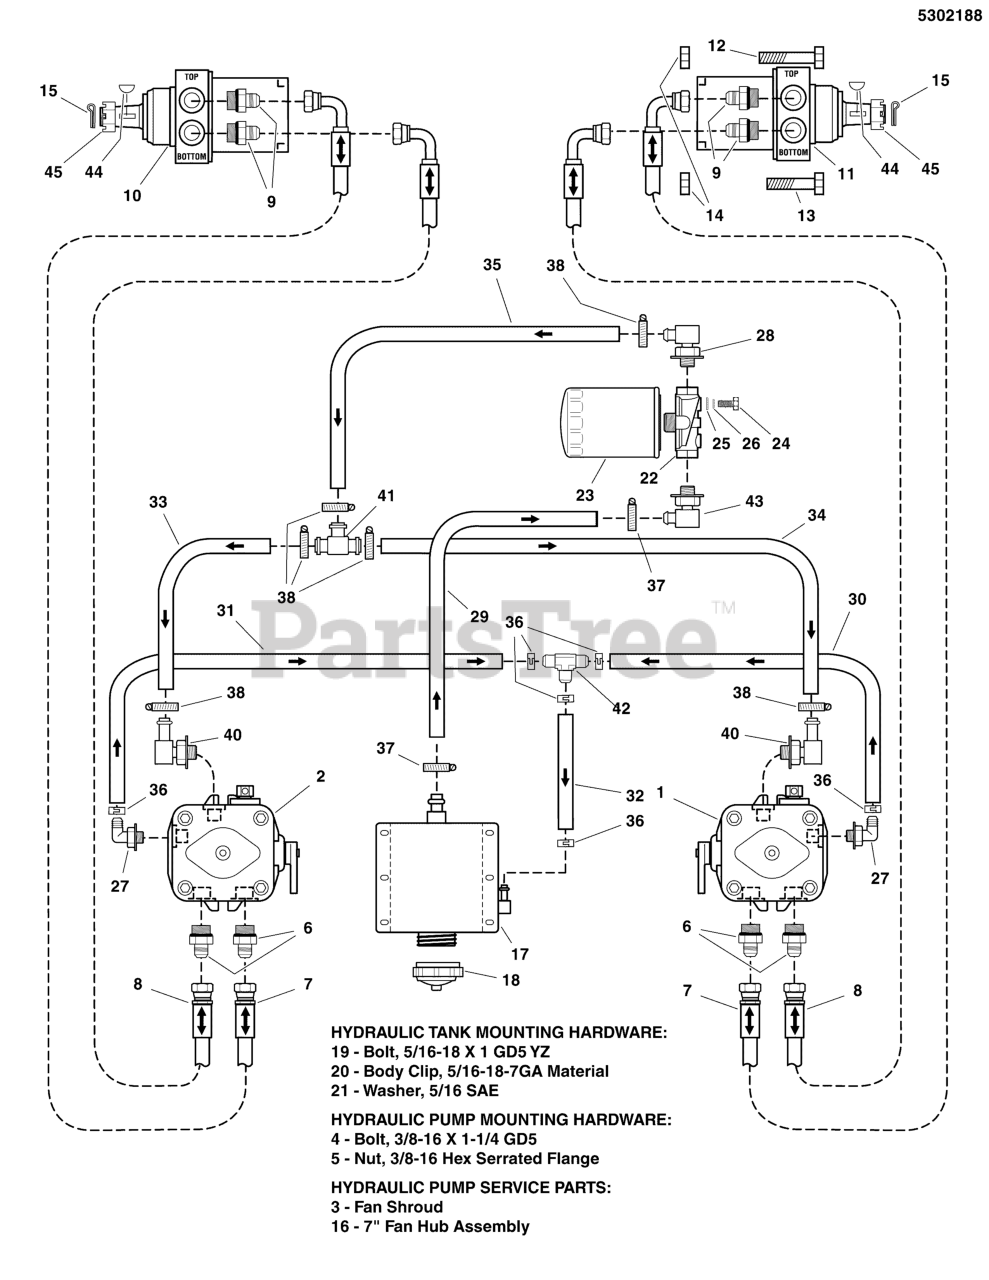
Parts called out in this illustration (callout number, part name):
1	PUMP, 16CC, PR-2KBQ-GV1F-XXXX
2	PUMP, 16CC, PR-2HBQ-GV1F-XXXX
3	FAN SHROUD
4	BOLT, 7/16-14 X 1-1/4 GD5 YZ
5	NUT, HEX, 7/16-14, SER, FLG, GD5, YZ
6	ADAPTER, HYD.
7	HOSE ASSEMBLY (33)
8	HOSE ASSEMBLY, (29)
9	ADAPTER, HYD.
10	WHEEL MOTOR, LH, 17.1 CI
11	WHEEL MOTOR, RH, 17.1 CI
12	BOLT, 1/2-13 X 2-1/2, NYLON PATCH
13	BOLT, 1/2-13 X 2-1/4 PATCH
14	NUT, 1/2-13 SQUARE
15	PIN, COTTER, 1/8 X 1-1/4
16	7" FAN HUB ASSEMBLY, HYDROGEAR #70811
17	RESERVOIR, HYDR, 3 QT
18	CAP, HYDRAULIC, SHIELDED VENT
19	BOLT, 5/16-18 X 1 GD5 YZ
20	BODY CLIP, 5/16-18-7GA MATERIAL
21	WASHER, 5/16" SAE
22	FILTER HEAD, HYDRAULIC
23	FILTER, OIL
24	BOLT, 1/4-20 X 3/4 GD5 YZ
25	WASHER, 1/4 SAE
26	WASHER, 1/4 LOCK
27	ADAPTER, 90 DEG, 9/16-3/8 BARB
28	FITTING, 9/16 O-RING-1/2" HOSE, 90 DEG
29	HOSE, 5/8 PUSH-LOCK, 4.25"
30	HOSE, 3/8" PUSH-LOCK, 11.50"
31	HOSE, 3/8" PUSH-LOCK, 29.25"
32	HOSE, 3/8" PUSH-LOCK, 19.50"
33	HOSE, 1/2" PUSH-ON, 21.00"
34	HOSE, 1/2" PUSH-ON, 12.00"
35	HOSE, 1/2" PUSH-ON, 3.00"
36	CLAMP, HOSE
37	CLAMP, #10 HOSE, STAINLESS
38	CLAMP, #6 HOSE, STAINLESS
39	CABLE TIE, 12
40	FITTING, EXTRA LG, 90, 1/2 TUBE - 3/4-16
41	FITTING, BEADED TEE, 1/2 X 1/2 X 1/2, YZ
42	FITTING, TEE, 1/2 HOSE
43	ADAPTER, 90 DEG, 9/16-3/8 BARB
44	KEY (SV)
45	NUT, CASTLE (SV)
